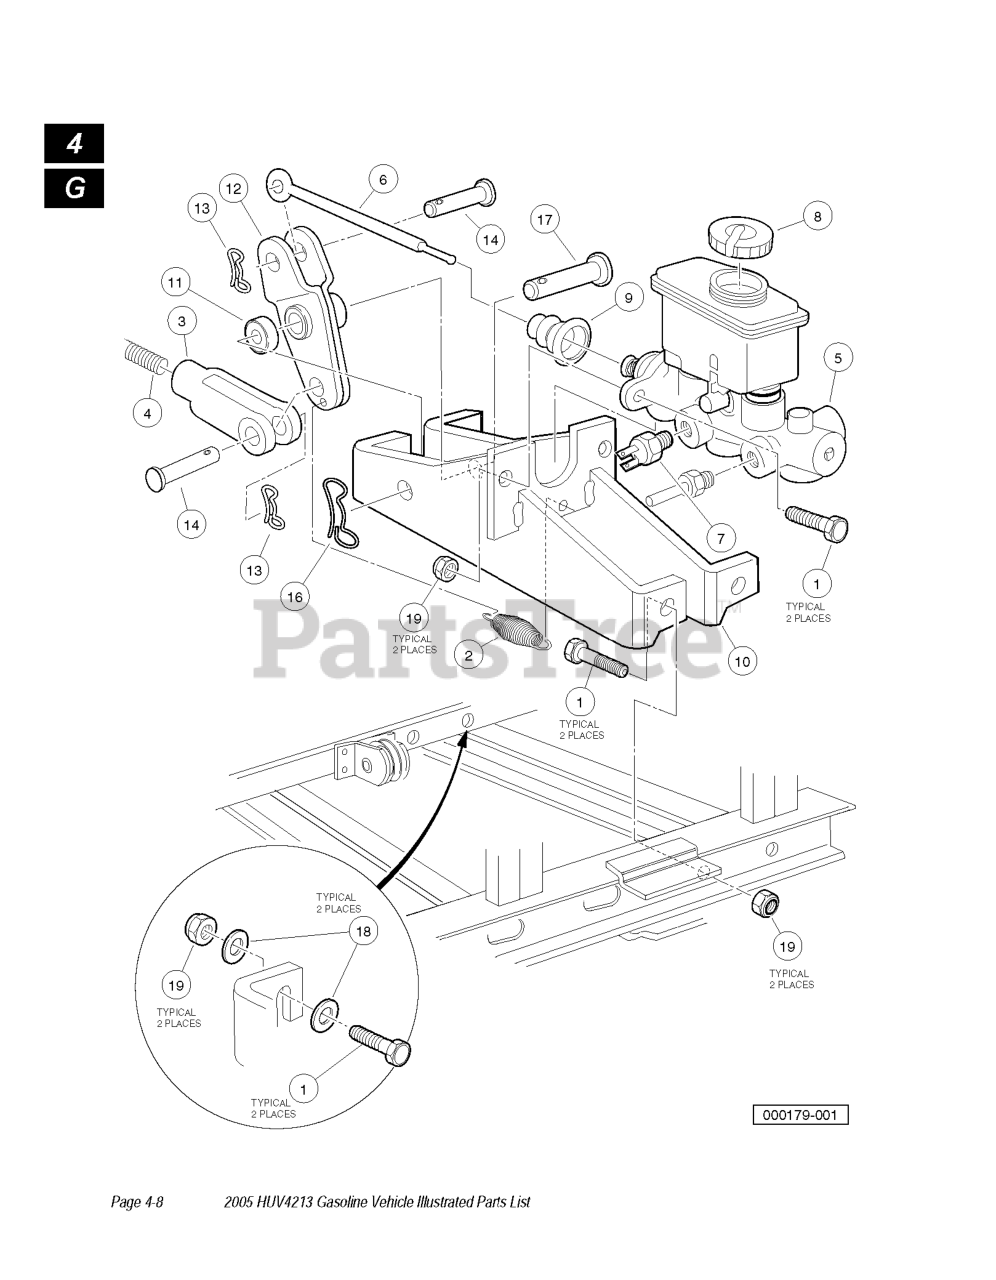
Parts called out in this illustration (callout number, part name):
1	SCREW HEX CAP
2	SPRING, BRAKE RETURN
4	EQUALIZER ROD
5	MASTER CYLINDER
7	PRESSURE SWITCH
8	FILLER CAP ASM
10	SUPPORT LEG BRACE ASM
12	BELL CRANK
13	PIN, BOW TIE LOCKING
14	PIN, 3/8 X 1-5/16 CLEVIS
15	PLUG, 3/8 X 24
16	PIN, BOW TIE .120X2.750
17	PIN, 1/2X2-1/2 CLEVIS
18	WASHER, 5/16 TYPE A FLAT
19	LOCKNUT, 5/16-18 NYLON INSERT
